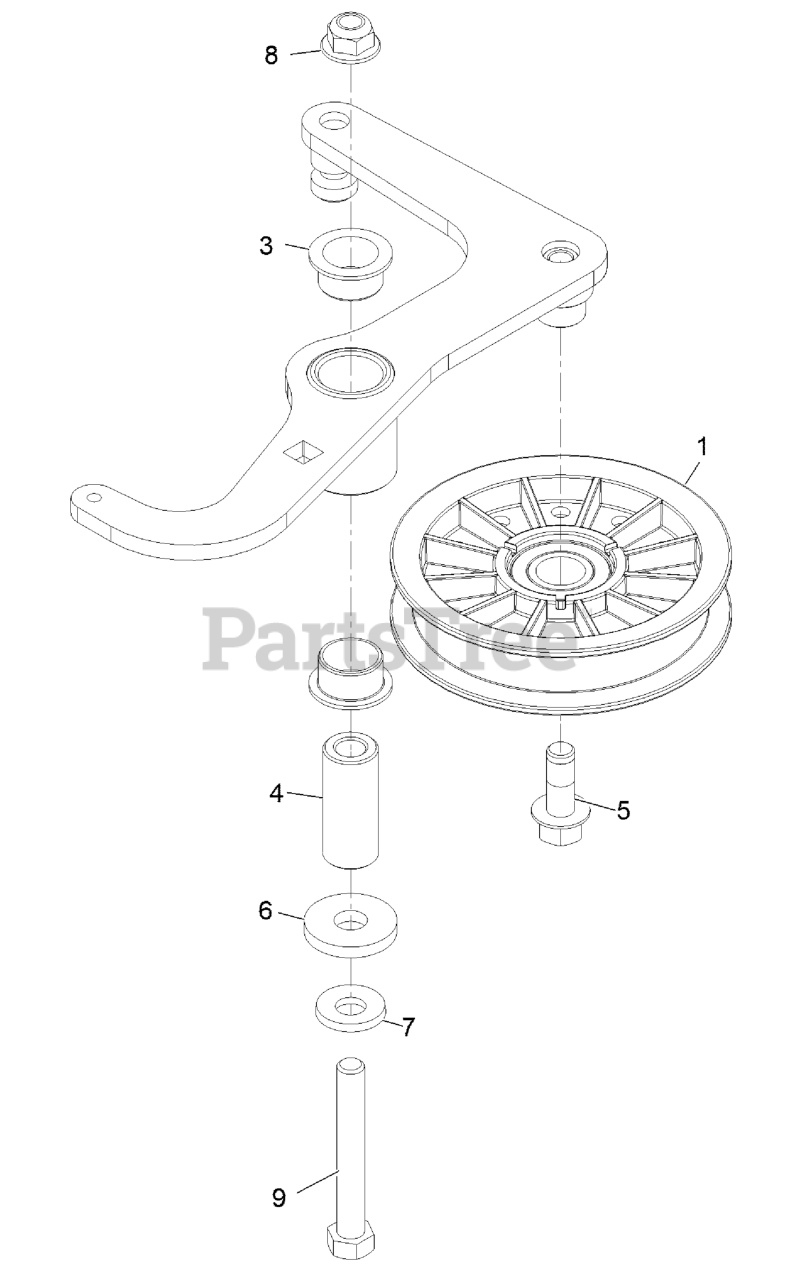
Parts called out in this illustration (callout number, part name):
1	PULLEY-IDLER, FLAT
3	BUSHING-FLANGE
4	SPACER, PIVOT
5	SCREW-HFH
7	WASHER-BELLEVILLE
8	NUT-HF, NI
9	SCREW-TAP
